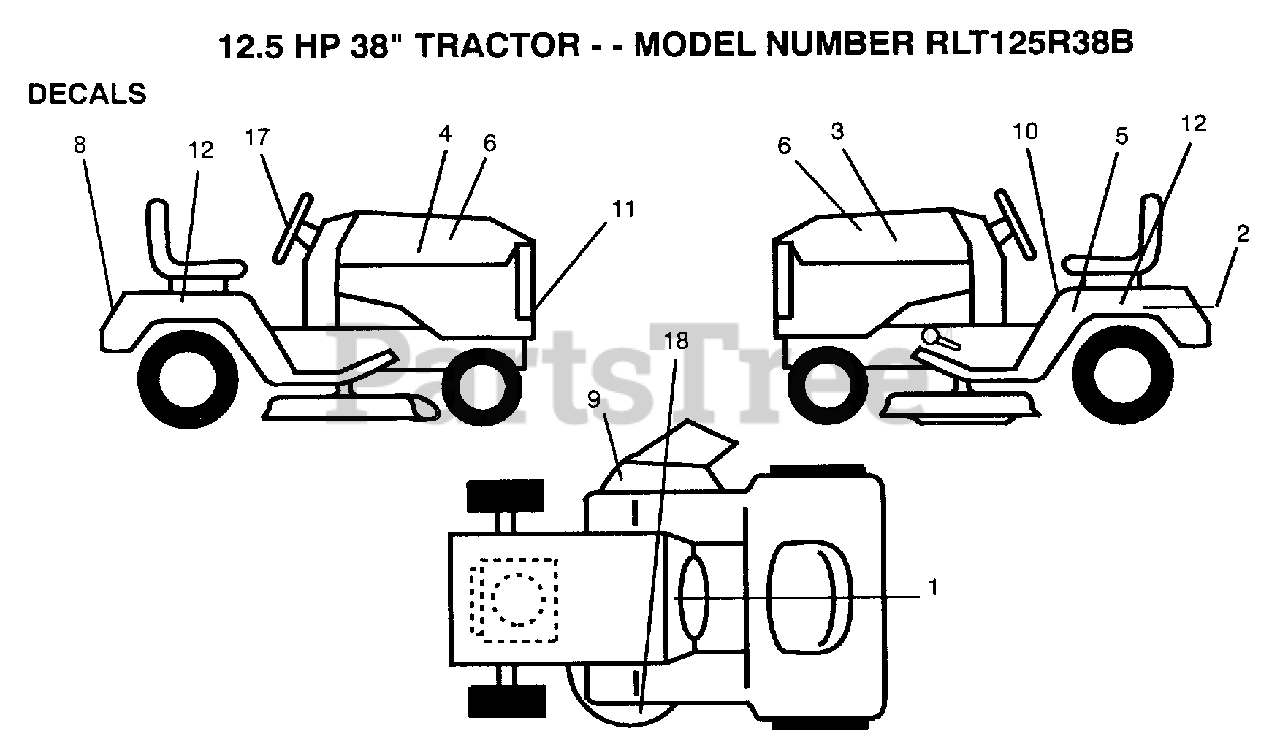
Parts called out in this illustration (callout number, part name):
2	DECAL
3	"DECAL,STP HD LH"
4	"DECAL,STP HD RH"
5	IND HGT DECK DECA
8	FENDER DECAL
9	"DECAL, WARNING"
10	DECAL CAUTION
11	GRILL DECAL
12	DECAL.FEND.QUICKS
17	"DECAL,STR WHL"
